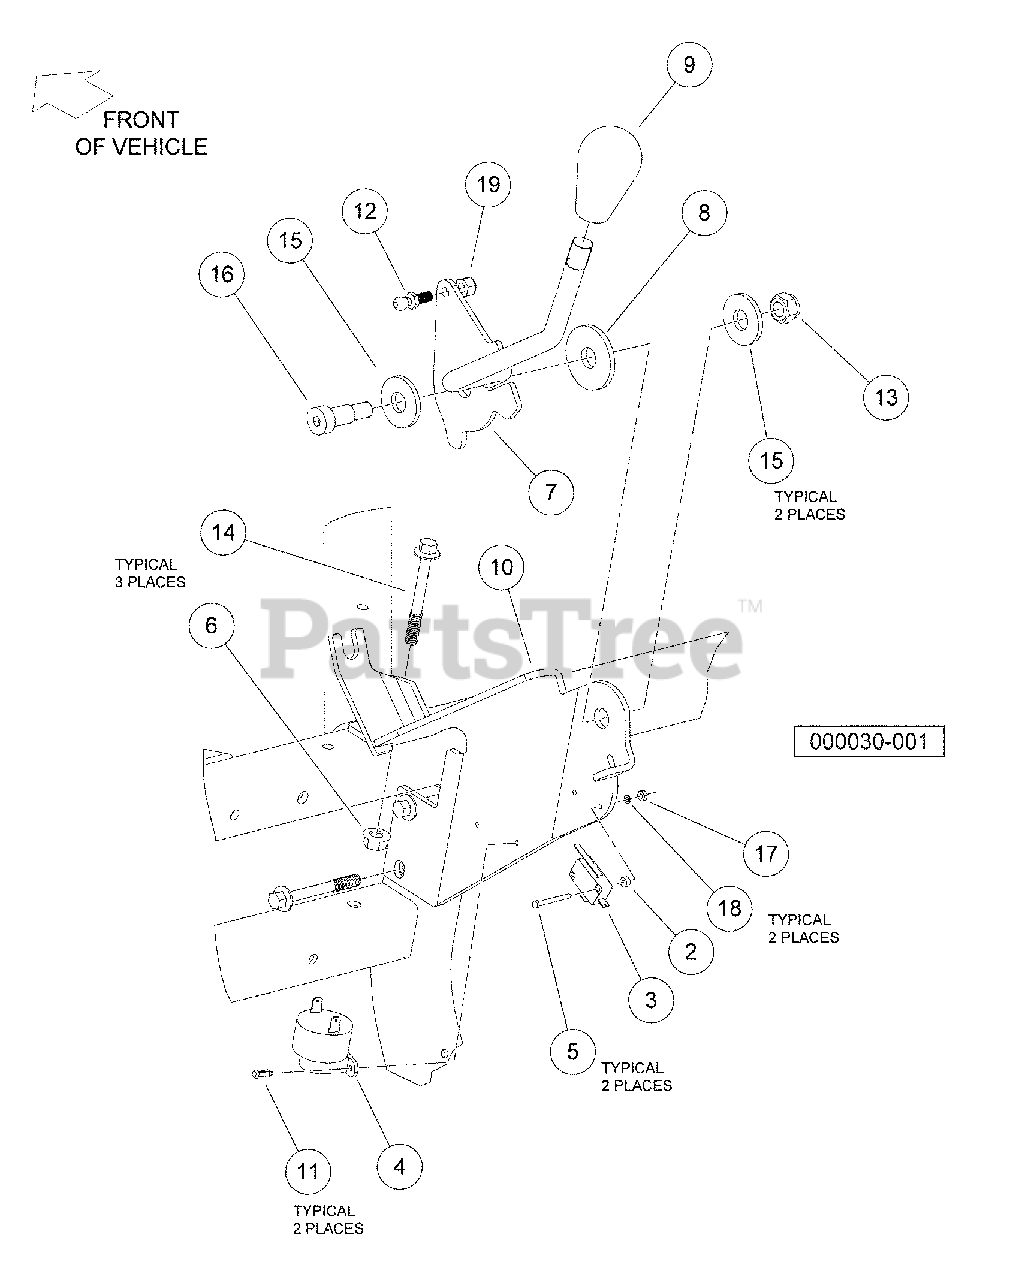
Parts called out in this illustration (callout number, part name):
1	Asm, FNR
2	Washer, #4 Nylon Flat
3	Switch, Limit
4	Buzzer, Reverse (9-48 VDC)
5	Screw, #4-40 X 1.125 Hx Hd Mch
6	Nut,m8,all Metal Lock
7	Weldment, FNR Shifter
8	Bushing, Fnr
10	Weldment, FNR Shifter Bracket
11	Rivet, Micro Tuflok
12	Stud, Ball, .346 Dia
13	Locknut, M10x1.5 Nylon Insert
14	Bolt Flanged Head, M8 X 1.25 X 65
15	Washer, M12 Hard Regular
16	Shoulder Bolt,m12 X 20 M10 Thd
17	Nut, #4-40 Hex Machine
18	Lockwasher, #4 Helical Split
19	Locknut, 1/4-28 Nylon Insert
